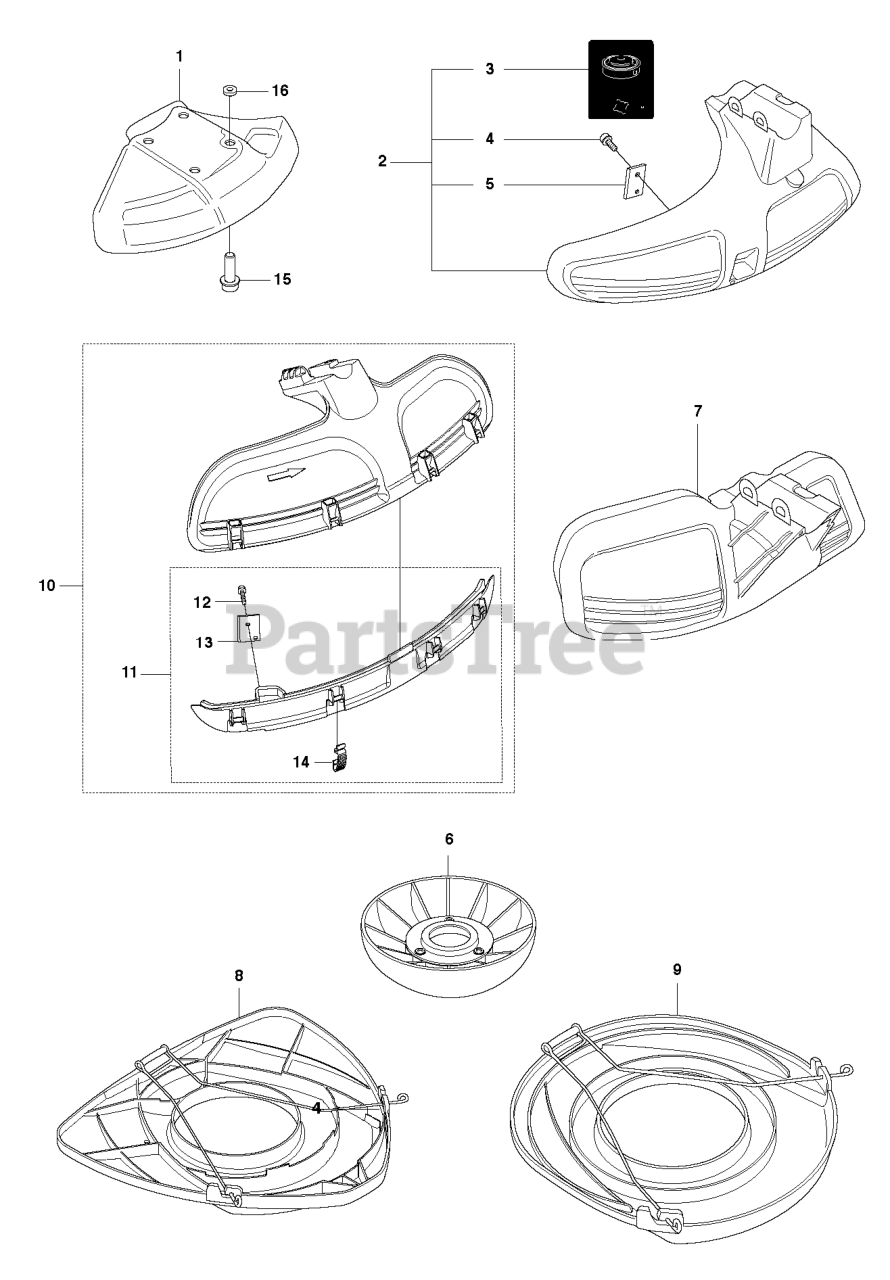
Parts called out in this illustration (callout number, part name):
1	BLADE GUARD
2	BLADE GUARD
5	LINE CUTTER
6	SUPPORTING CUP
7	BLADE GUARD
8	TRANSPORT GUARD
9	BLADE GUARD TRANSPORT
10	COMBINATION GUARD
11	SPLASH GUARD
13	LINE CUTTER
16	LOCKING NUT
